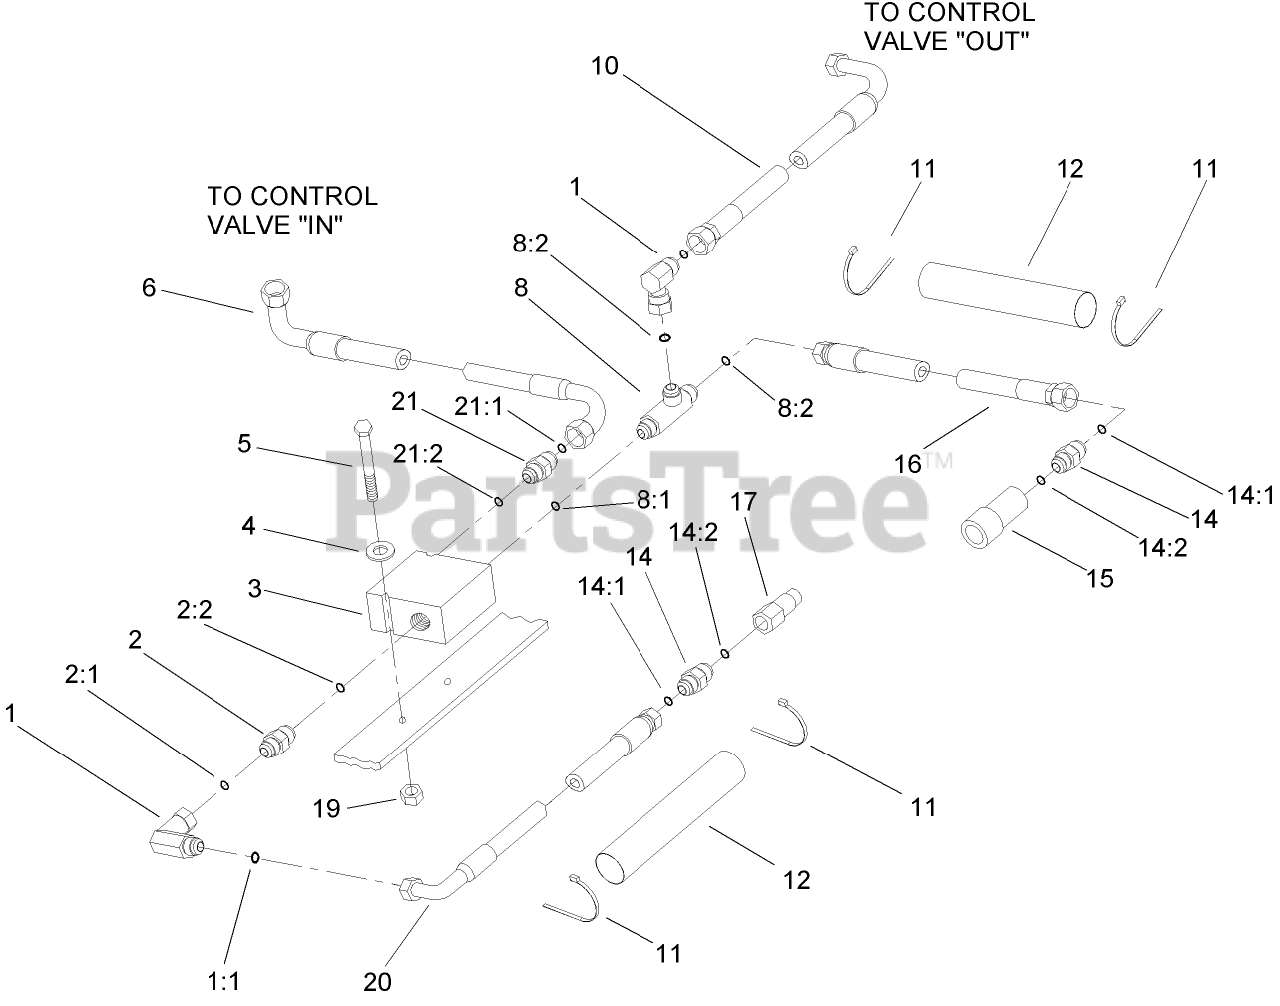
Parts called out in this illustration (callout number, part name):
1	FITTING-HYD
1:1	O-RING
2	FITTING-STRAIGHT
2:1	O-RING
2:2	O-RING
3	DIVIDER-FLOW
4	WASHER-FLAT
5	SCREW-HH
6	HYDRAULIC HOSE ASM
8	FITTING-TEE
8:1	O-RING
8:2	O-RING
10	HYDRAULIC HOSE ASM
11	TIE-CABLE
12	SLEEVE-HOSE
14	FITTING-STRAIGHT
14:1	O-RING
14:2	O-RING
15	COUPLER-FACE, FLUSH
16	HYD HOSE ASM
17	NIPPLE-CONNECT, PRESSURE
19	NUT-LOCK, NI
20	HYDRAULIC HOSE ASM
21	FITTING-STR
21:1	O-RING
21:2	O-RING
